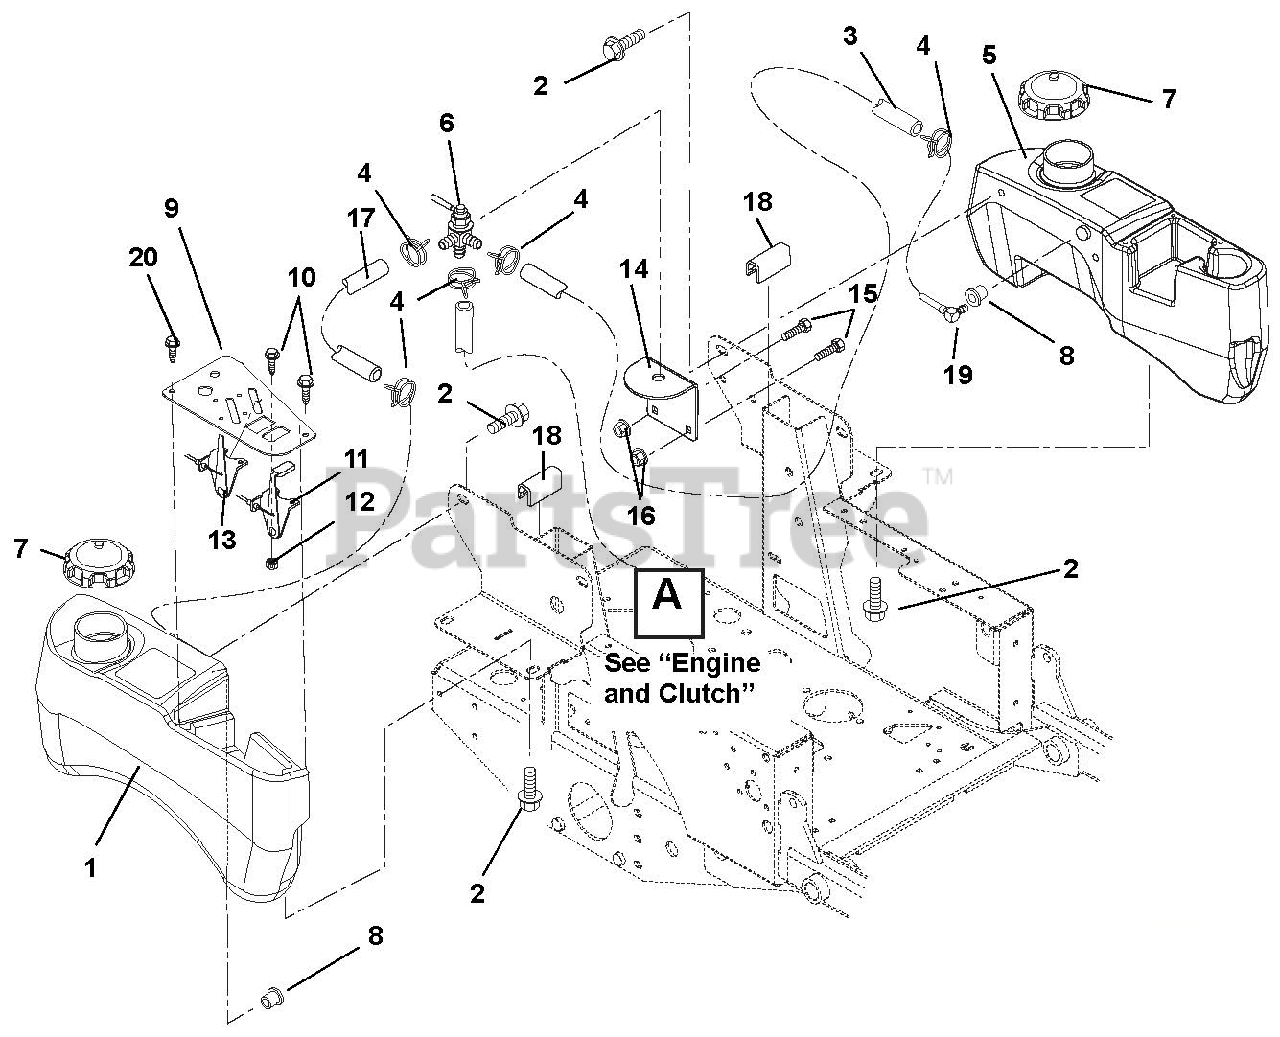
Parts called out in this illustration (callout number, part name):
1	Tank, Fuel Right Hand
2	Bolt, SEMS .31-18 x .62
3	Hose, Gas Line .25" I.D.
4	Hose, Clamp
5	Tank, Fuel Left Hand
6	Valve, Fuel
7	Cap, Fuel Non-Vent Autolock
7	Cap, Fuel Vent-In Autolock
8	Grommet
9	Panel, Control
10	Screw, Machine 10-24 x .50 Hex Washer Head
11	Cable, Throttle
12	Nut, Locking Nylon 10-24 with Insert
13	Cable, Choke
14	Bracket, Fuel Valve Mounting
15	Bolt, Round Head Square Neck .31-18 x .75 Grade 5
16	Nut, Nyloc Flange 5/16-18
17	Hose, Gas Line .25" I.D.
18	Cowl Strip 1.75" Long
19	Assembly, Small Tank Fuel Pick-up
20	Screw, Machine 10-24 x .38
